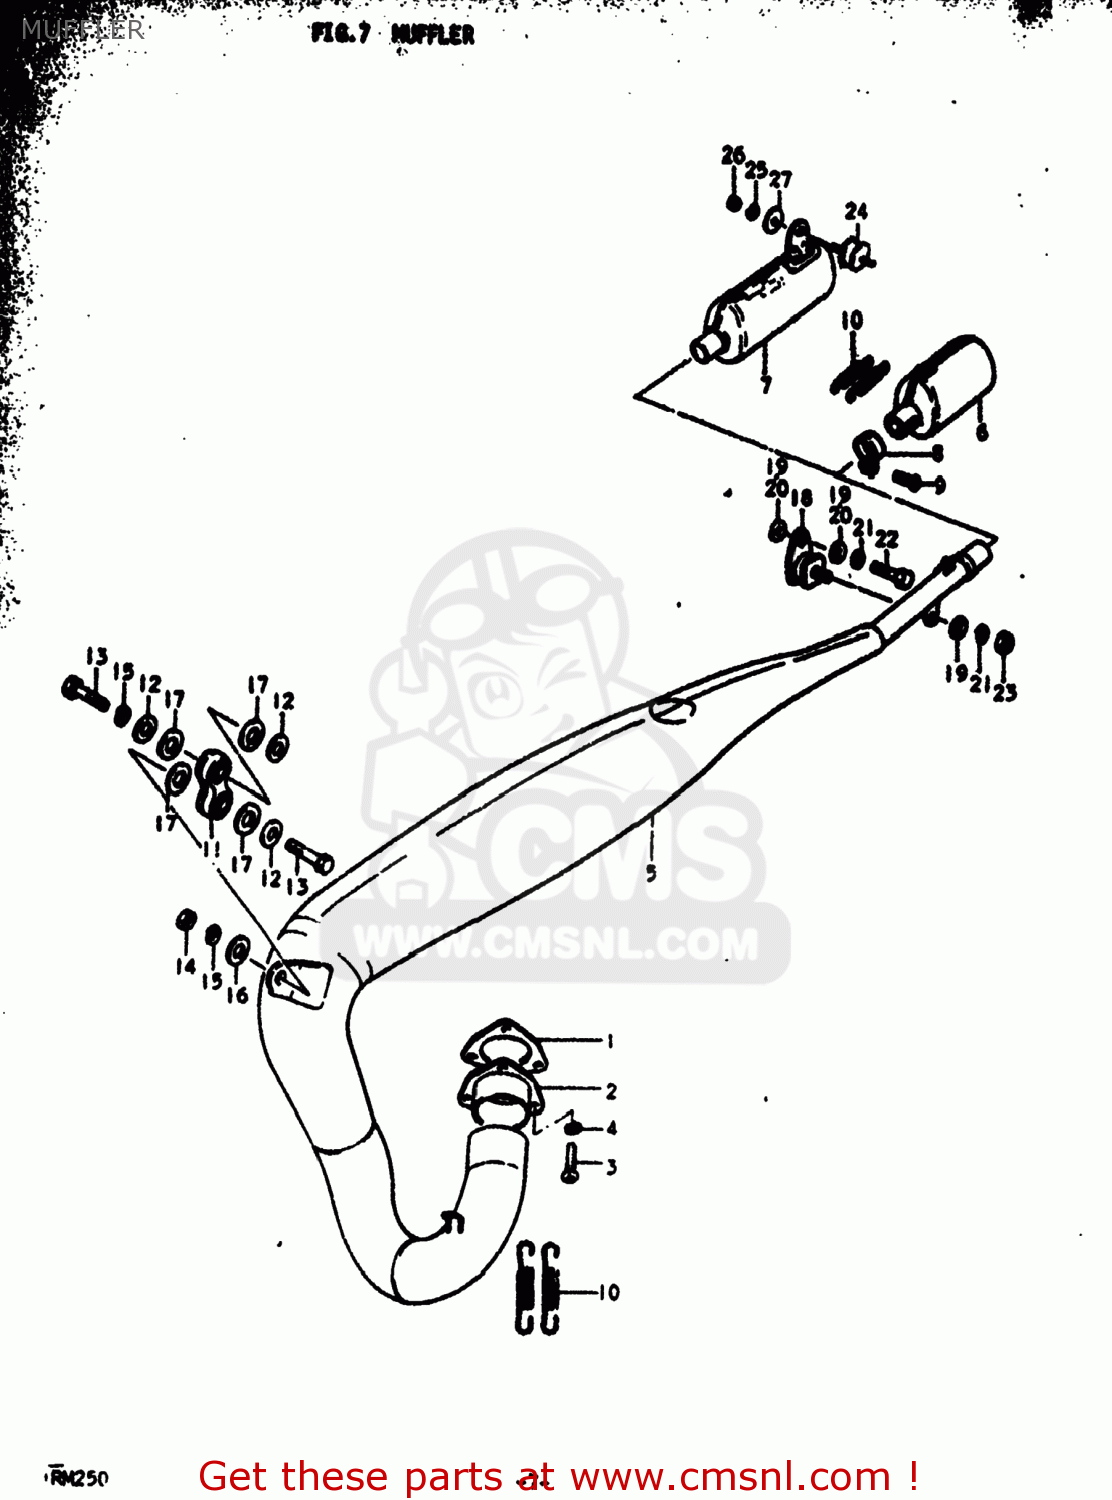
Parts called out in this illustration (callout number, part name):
1	GASKET,EXHAUST PIPE (MCA)
2	FLANGE,EXHAUST PIPE
3	SCREW
4	LOCK WASHER
5	BODY,MUFFLER
6	BODY,MUFFLER
7	BODY,MUFFLER
8	CLAMP
9	BOLT(6X20)
10	SPRING
11	DAMPER,MUFFLER
12	WASHER
13	BOLT
14	NUT
15	LOCK WASHER
16	WASHER
17	WASHER(13X28X1.6)
18	DAMPER,MUFFLER SUPPORT
19	WASHER
20	WASHER (8.2X20X1.6)
21	LOCK WASHER
22	BOLT 8X16
23	NUT
24	DAMPER,MUFFLER SUPPORT
25	LOCK WASHER
26	NUT
27	WASHER (8.2X20X1.6)
